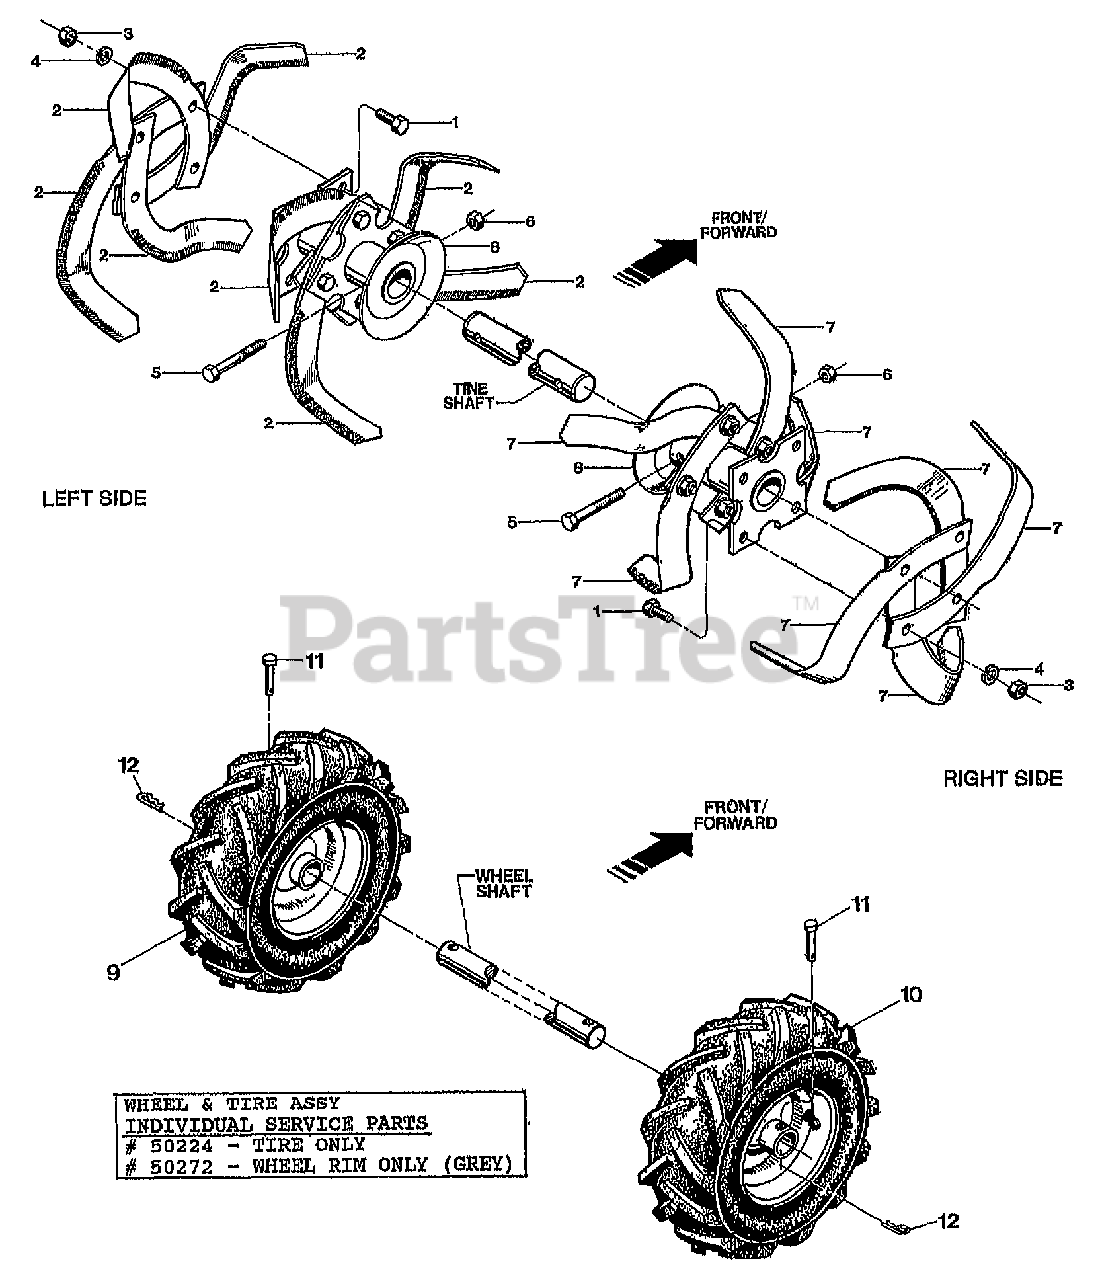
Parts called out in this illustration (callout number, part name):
1	SCR-HH 3/8-16X1.0 G5 ZP
2	TINE-BOLO RH TINE USED ON LH SIDE OF TILLER
3	NUT-HEX 3/8-16 ZP
4	WASHER-LK .375 @ DEPL
5	SCR-HH 3/8-16X2.00 G8
6	NUT-H/LK 3/8-16
7	TINE-BOLO LH TINE USED ON RH SIDE OF TILLER
8	HOLDER-TINE JUNIOR LEFT & RIGHT SIDES
9	ASSM-WHEEL&TIRE LT
10	ASSM-WHEEL&TIRE RT
11	PIN-CLEVIS SECURES WHEEL HUB TO WHEEL SHAFT
12	PIN-CLIP .08
